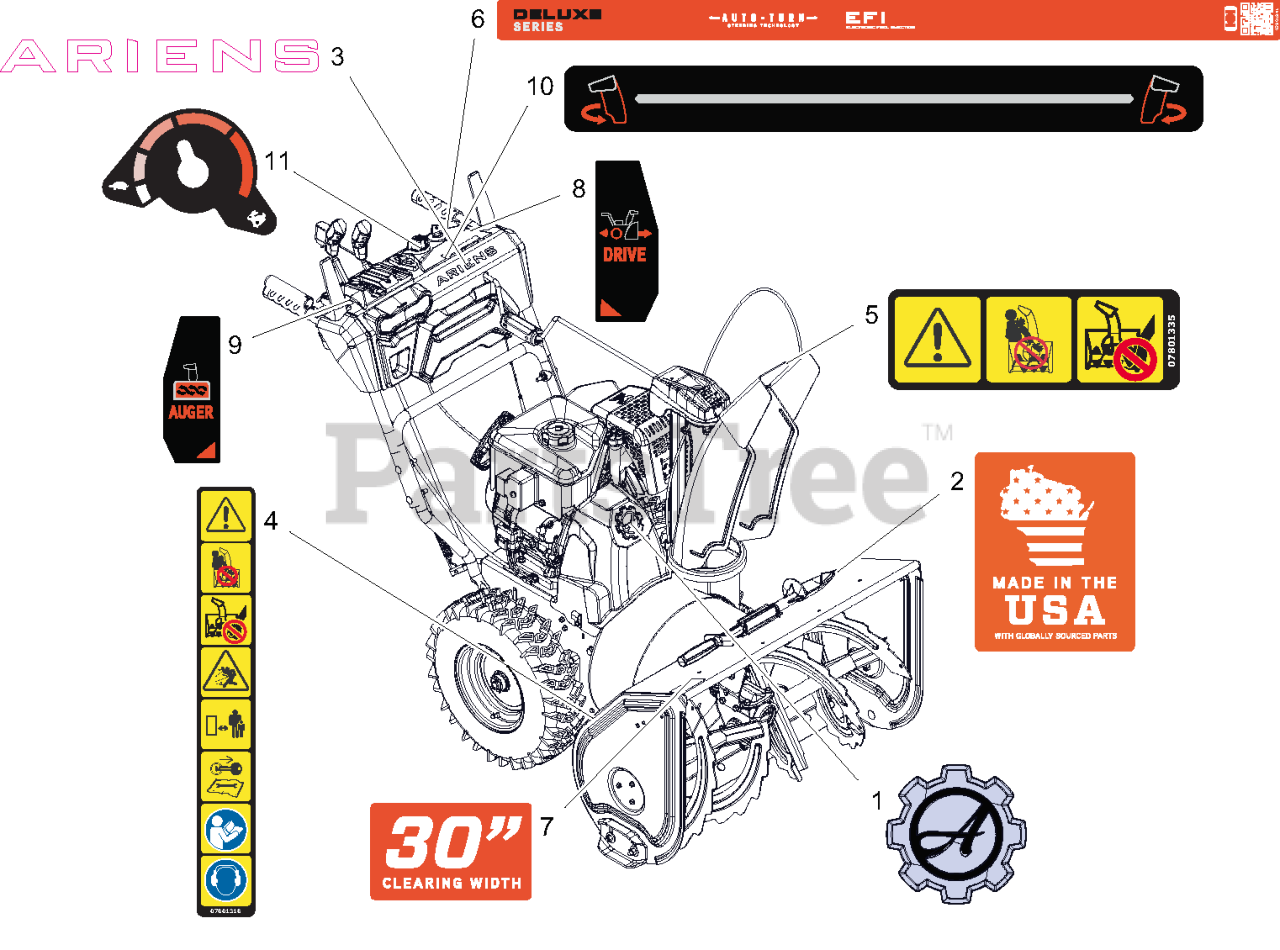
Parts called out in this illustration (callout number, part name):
1	DECAL, ARIENS - GEAR BADGE
2	DECAL- MADE IN USA
3	DECAL- ARIENS - 7.46"
4	DECAL- SAFETY - DANGER
5	DECAL- DANGER
6	DECAL- DASH - DLX EFI
7	DECAL- CLEARING - 30
8	DECAL- CONTROL - DRIVE WHEEL
9	DECAL- CONTROL - AUGER
10	DECAL- CHUTE ROTATION
11	DECAL- CONTROL - EFI SPEED
